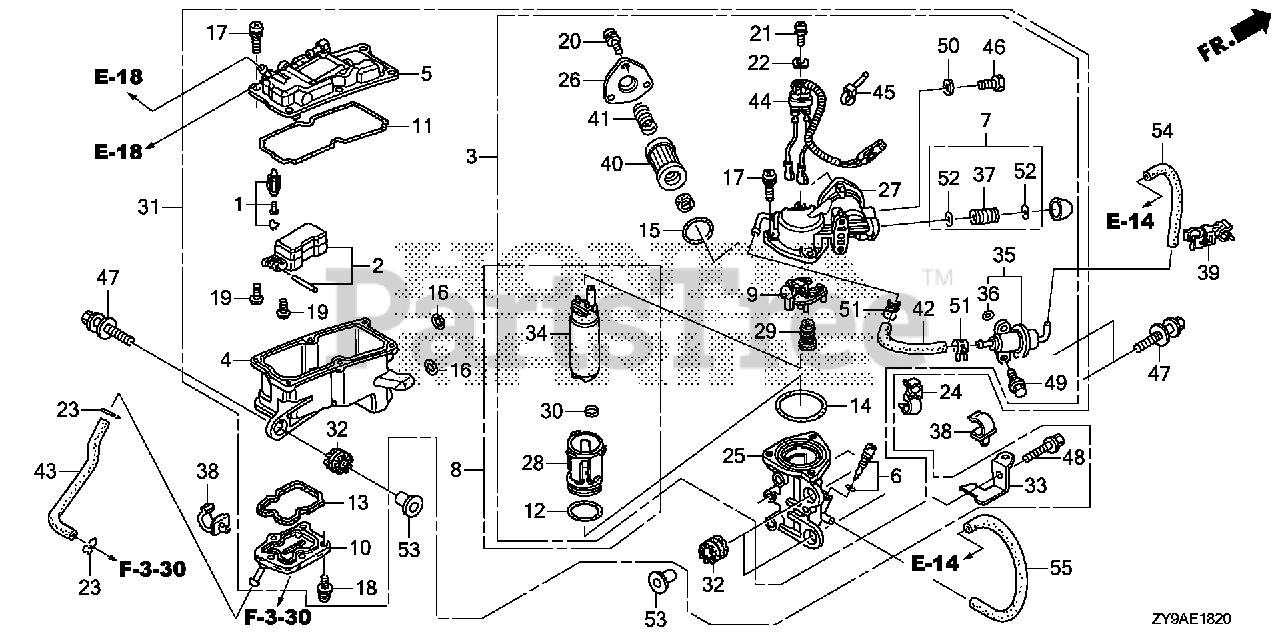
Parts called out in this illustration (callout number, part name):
1	VALVE SET, FLOAT
3	PUMP UNIT, FUEL (A) (MSDS)
6	SCREW SET, DRAIN
8	PUMP UNIT, FUEL (B) (MSDS)
10	COVER, WATER JACKET
17	SCREW-WASHER
18	SCREW-WASHER
19	SCREW, PAN
20	SCREW-WASHER
21	SCREW, WASHER
22	WASHER, PLAIN
23	CLIP, TUBE
24	CLAMP, CHECK VALVE
25	CASE, PUMP
26	COVER B, PUMP
27	COVER, PUMP (A)
29	INSULATOR
31	SEPARATOR ASSY., VAPOR
32	GROMMET, VAPOR SEPARATOR
33	STAY, FUEL TUBE
34	PUMP UNIT, FUEL (MSDS)
35	REGULATOR ASSY., PRESSURE
36	O-RING, PRESSURE REGULATOR
37	JOINT, FUEL PIPE
38	CLAMP B, FUEL TUBE
39	CLAMP D, FUEL TUBE
40	SCREEN, FUEL STRAINER
41	SPRING, COMPRESSION
42	HOSE, PRESSURE REGULATOR RETURN
43	TUBE A, WATER
46	BOLT, SEALING (6MM)
47	BOLT-WASHER (8X35)
48	BOLT, FLANGE (6X25)
49	BOLT, FLANGE (6X14)
50	WASHER, SEALING (6MM)
51	CLAMP, TUBE (D10.7)
52	O-RING (7.8X1.9) (ARAI)
53	COLLAR (8.5X14.5)
54	BULK HOSE, FUEL (3.5X3000) (3.5X120)
55	BULK HOSE, VINYL (5X9X1000) (5X9X240)
